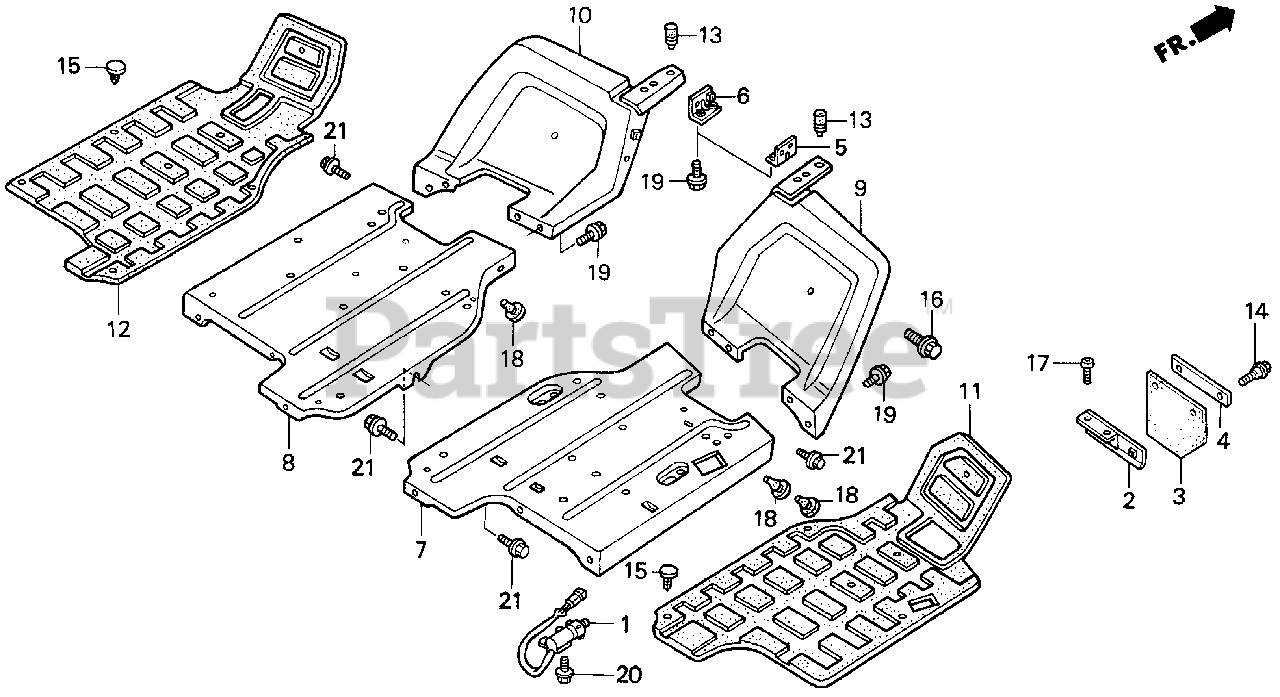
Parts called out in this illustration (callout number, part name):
1	SWITCH ASSY., BRAKE
2	BRACKET, SPLASH GUARD
3	SPLASH GUARD, ACCELERATOR
4	PLATE, SPLASH GUARD MOUNTING
5	BRACKET, R. COLUMN COVER
6	BRACKET, L. COLUMN COVER
7	STEP, R. *R165* (JOLLY RED)
8	STEP, L. *R165* (JOLLY RED)
9	FENDER, R. FR. *R165* (JOLLY RED)
10	FENDER, L. FR. *R165* (JOLLY RED)
11	FLOOR MAT, R.
12	FLOOR MAT, L.
13	STOPPER, TAILGATE (BLACK)
14	BOLT, FLANGE (6MM)
15	CLIP, MAT (5MM) *NH1L* (BLACK)
16	BOLT-WASHER (6X12)
17	SCREW, PAN (6X12)
18	RUBBER B, STAND STOPPER
19	BOLT, FLANGE (6X12)
20	BOLT, FLANGE (6X14)
21	BOLT, FLANGE (6X16)
